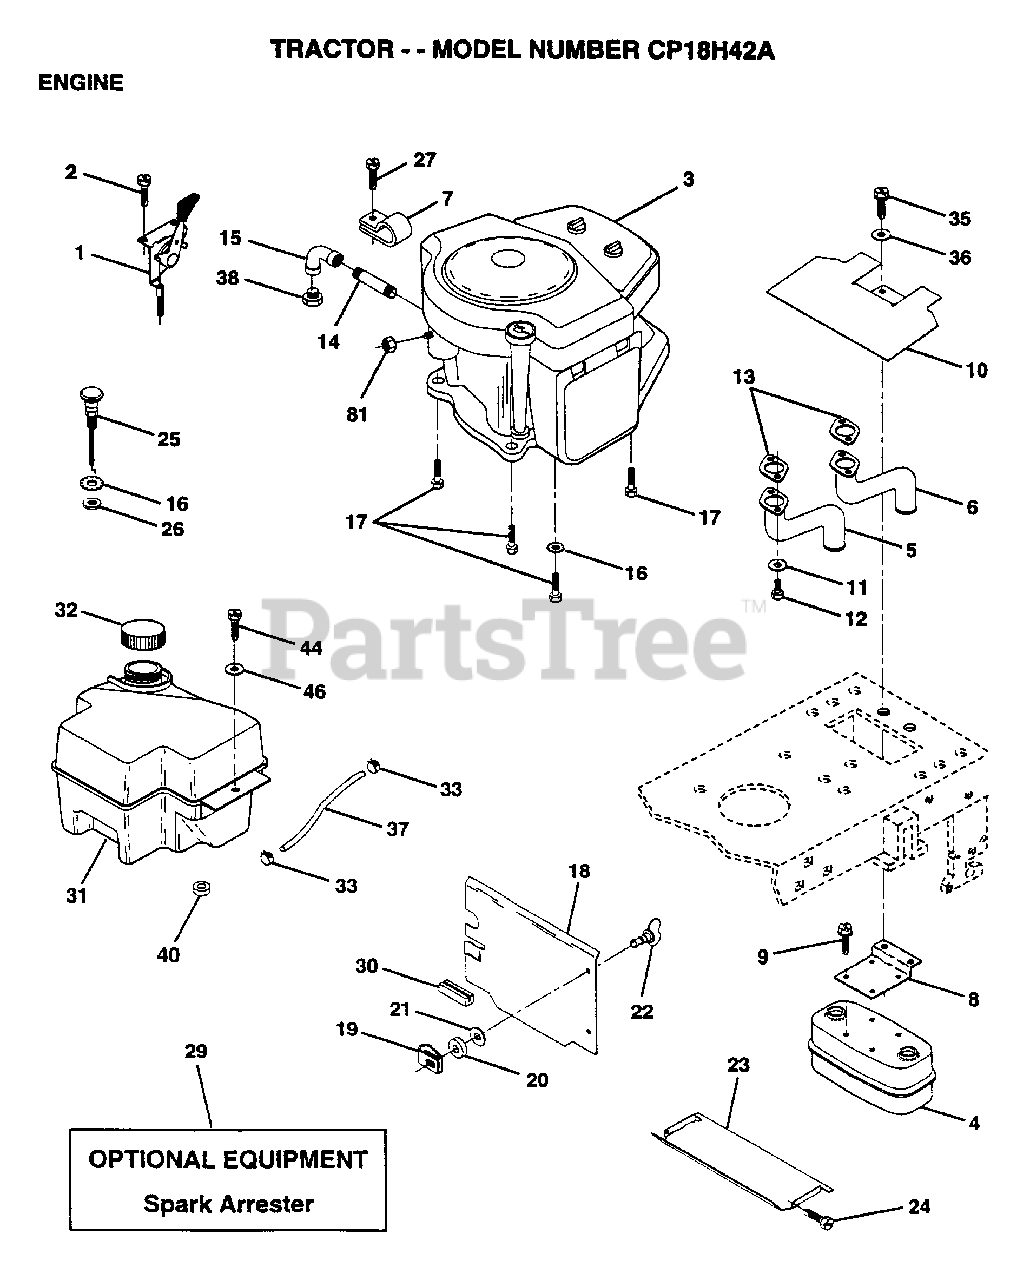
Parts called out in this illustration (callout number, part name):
1	CONTROL THRT 35.5
2	SCREW LT
3	ENGINE B&S 18HP
5	EXHAUST.B&S.18.LH
6	EXHAUST.B&S.18.RH
7	CLAMP.TUBE.DBL.EN
8	BRACKET MUFFLER
9	SCREW ST
10	SHIELD.HEAT.
11	LOCKWASHER
14	PIPE NIPPLE LT
15	ELBOW
16	LOCKWASHER
17	SCREW LT
18	SHIELD HEAT
19	RECEPTACLE LT
20	RETAINER LT
21	WASHER
22	STUD.1/4.TURN
24	SCREW
25	CONTROL CHOKE
27	SCREW.10-24X1/2
32	CAP ASM FUEL
33	HOSE CLAMP
35	SCREW
36	WASHER
37	LINE FUEL
44	SCREW HEX CRT
46	WASHER
81	NUT
